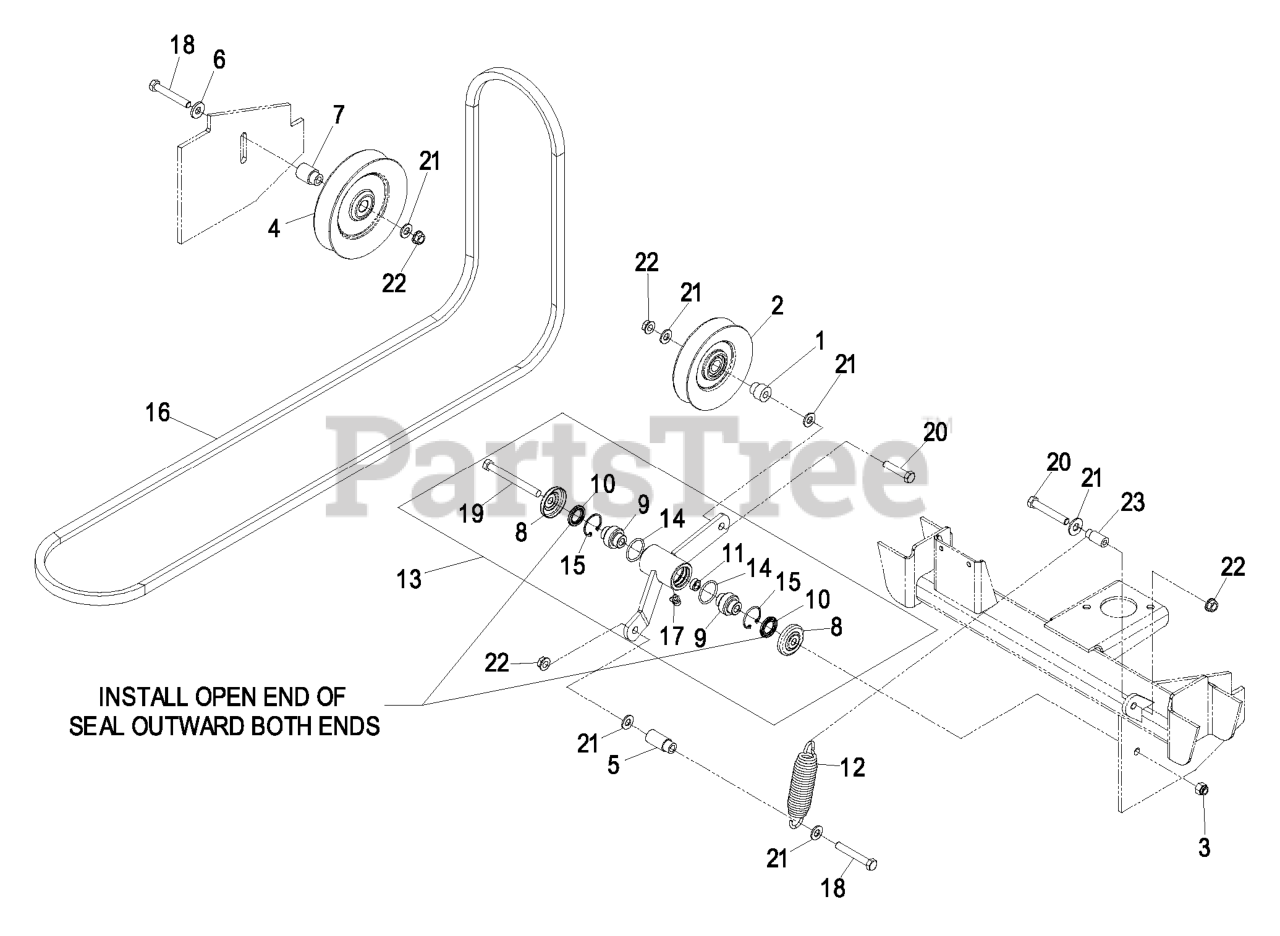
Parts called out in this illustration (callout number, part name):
1	BUSHING-IDLER
2	PULLEY-IDLER
3	NUT-LOCK, NI
4	PULLEY-IDLER
6	WASHER-BELLEVILLE
7	BUSHING-IDLER
8	GUARD-TOP
9	BEARING-SPHERICAL
10	SEAL-LIP, SINGLE
15	RING-SNAP
16	BELT,B 123.2
17	FITTING-GREASE, 90 DEG
18	BOLT-CARR
19	SCREW-HH
20	SCREW-HH
21	WASHER-FLAT
22	NUT-HHF, WHIZ
23	SPACER-TIGHTENER, BELT
